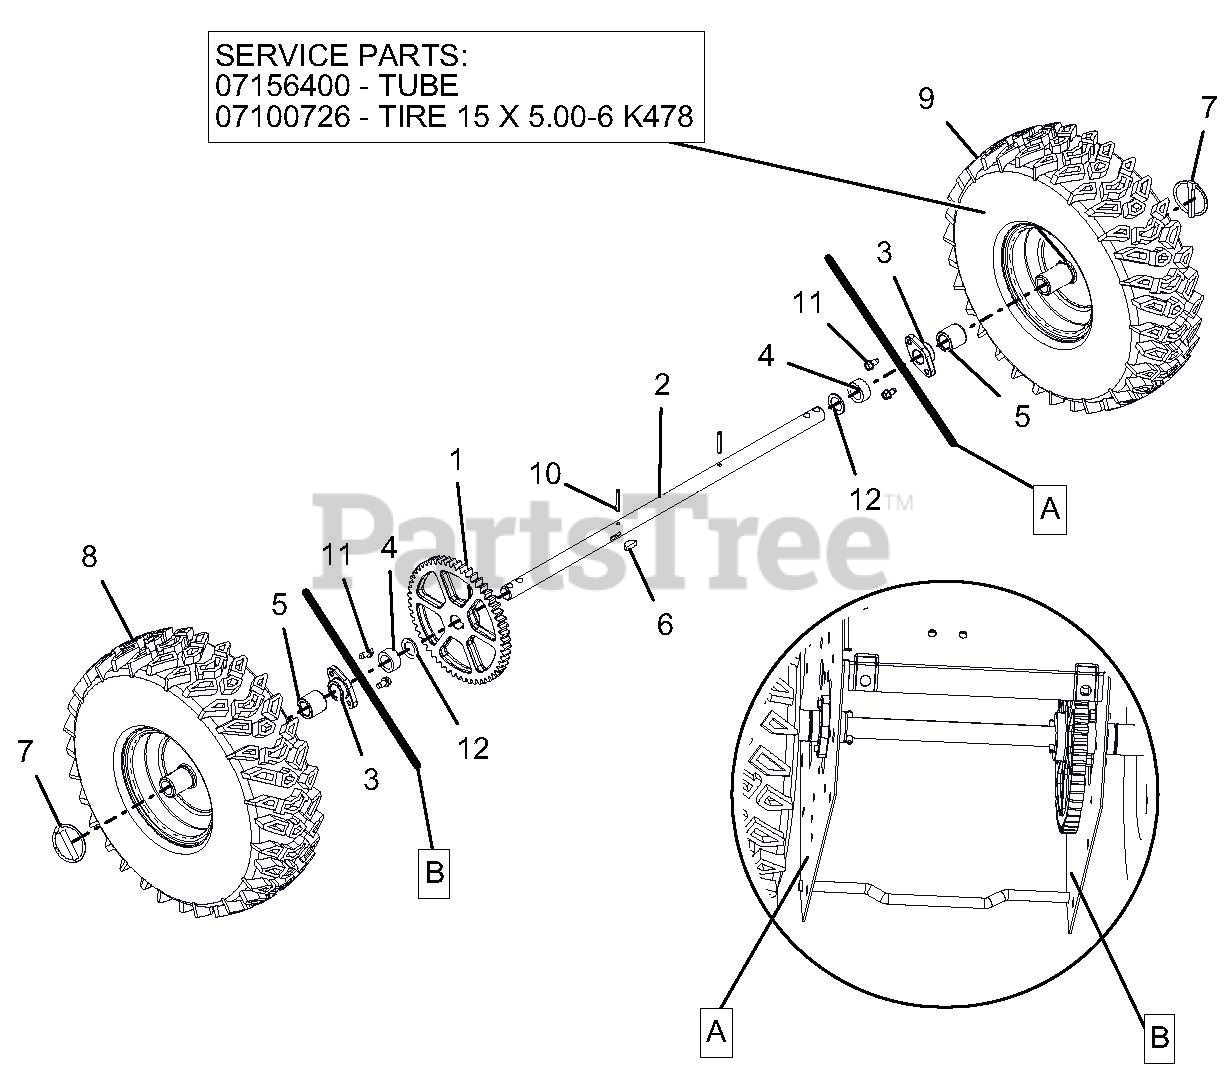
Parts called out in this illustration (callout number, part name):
1	SPUR GEAR, 54T .75ID X 6.75PD
2	AXLE, COMPACT 920,XXX 15" TIRE
3	BSHG .75X1.125X.65
4	BSHG-SLV .766 X 1.125 X .500
5	BSHG-SLV .75X1.12X1.062 NYL BK
6	KEY-WDRF .25X.750X.313 SAE91
7	PIN-LOK .31X1.75
8	TIRE/WHEEL, RH 15X5.00-6 PIN
9	TIRE/WHEEL, LH 15X5.00-6 PIN
10	PIN-ROLL .188X1.25
11	SCR-TAP .25-20X.50 HWH TR YWZ
12	WSHR-FL-STL.754X1.125X.062YWZC
13	TUBE 15 X 5.00-6
14	TIRE, 15X5.00-6 K478
